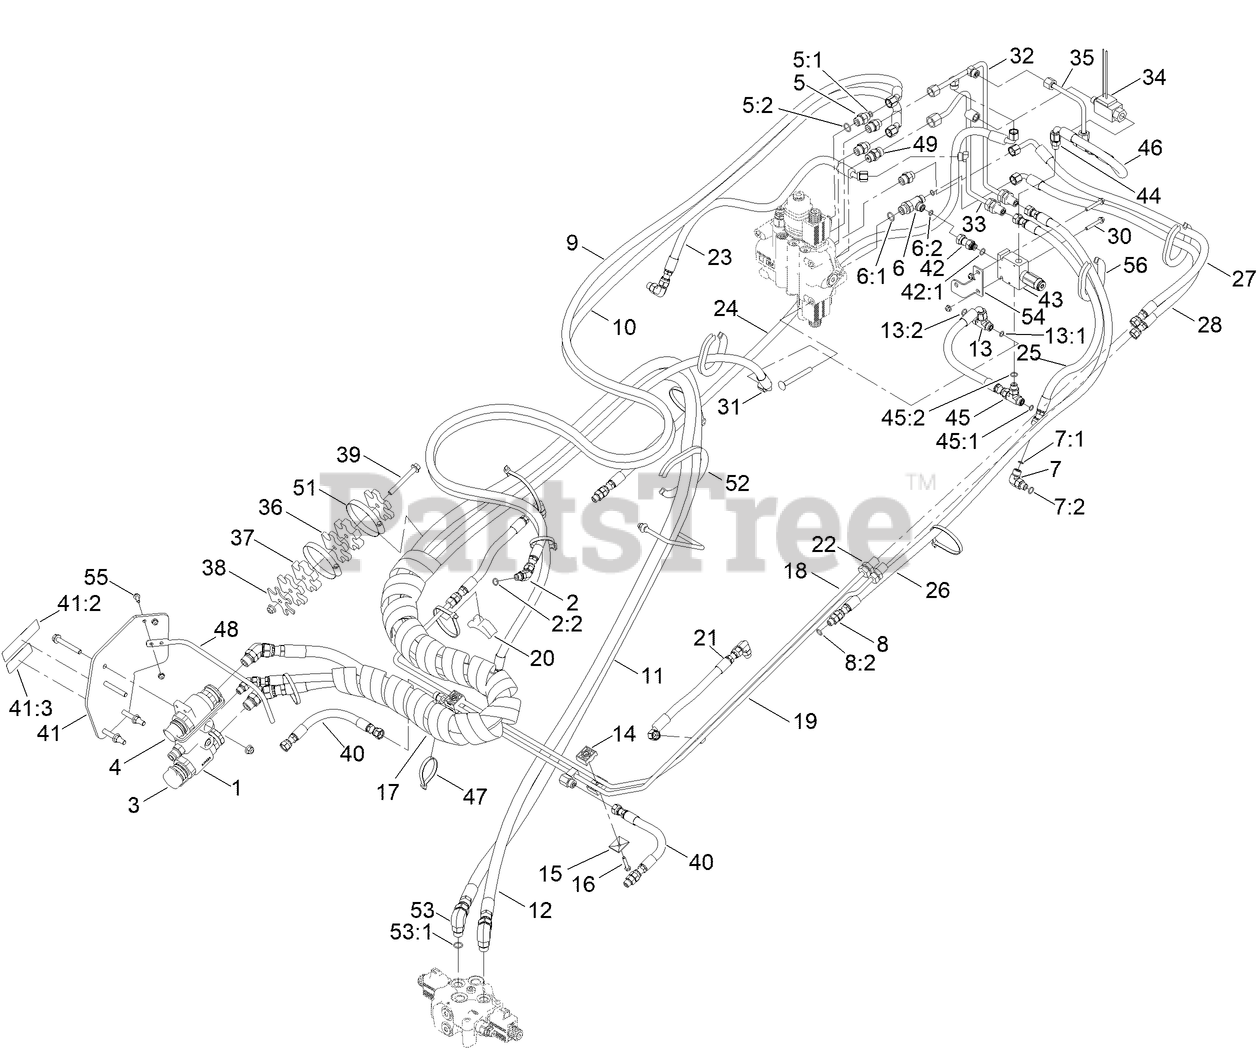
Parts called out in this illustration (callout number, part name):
1	MANIFOLD-QDC
2	FITTING-ELBOW, 45 DEG
2:2	O-RING
3	CAP-DUST, COUPLER
4	CAP-DUST, NIPPLE
5	FITTING-STRAIGHT
5:1	O-RING
5:2	O-RING
6	FITTING-HYD, TEE
6:1	O-RING
6:2	O-RING
7	FITTING-ELBOW, 90 DEG
7:1	O-RING
7:2	O-RING
8	FITTING-STRAIGHT
8:2	O-RING
9	HYD HOSE ASM
10	HYD HOSE ASM
11	HYD HOSE ASM
12	HYD HOSE ASM
13	FITTING-TEE
13:1	O-RING
13:2	O-RING
14	CLAMP-HOSE
15	PLATE-CLAMP, RETAINER
16	SCREW-HH
17	WRAP-HOSE
18	HYD TUBE ASM
19	HYD TUBE ASM
20	BLOCK-HARDLINE
21	HYD HOSE ASM
22	NUT-LOCK
23	HYD HOSE ASM
24	HYD HOSE ASM
25	HYD HOSE ASM
26	HYD HOSE ASM
27	HYD HOSE ASM
28	HYD HOSE ASM
30	SCREW-HHF
31	HYD HOSE ASM
32	HYD TUBE ASM
33	HYD TUBE ASM
34	SWITCH-PRESSURE,
35	HYD TUBE ASM
36	CLAMP-HOSE
37	CLAMP-HOSE
38	PLATE-BACKER
39	SCREW-HHF
40	HYD HOSE ASM
41	MOUNT-QC
41:2	DECAL-CAUTION
41:3	DECAL-WARNING, HYD PRESSURE
42	CONNECTOR-SWIVEL, STRAIGHT
42:1	O-RING
43	VALVE-SEQUENCE
44	FITTING-STRAIGHT
45	ADAPTER
45:1	O-RING
45:2	O-RING
46	HYD HOSE ASM
47	TIE-CABLE
48	GUIDE-HOSES
49	VALVE-CHECK
51	CLAMP-BAND/SCREW
52	TRIM-SEAL
53	FITTING-ELBOW, 90 DEG
53:1	O-RING
54	BRACKET-MOUNT, VALVE
55	SCREW-HHF
56	TRIM-SEAL
